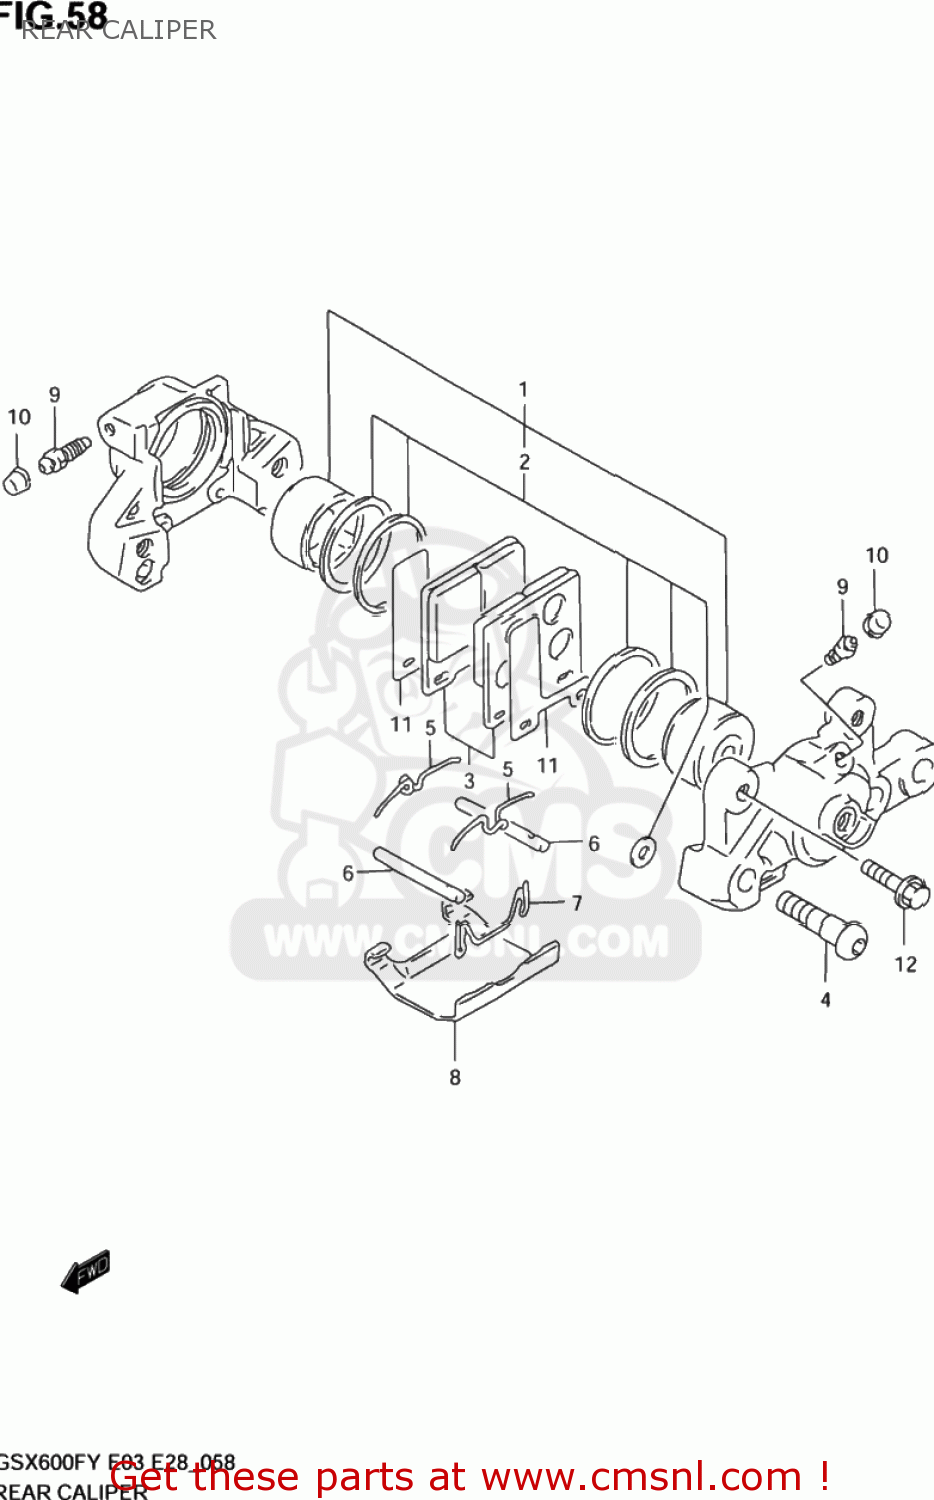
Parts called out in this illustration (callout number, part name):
1	PISTON SET
2	SEAL SET,PISTON
3	PAD SET (NAS)
4	BOLT,HOUSING
5	SPRING
6	PIN,PAD
7	CLIP,PAD PIN
8	COVER
9	BLEEDER
10	CAP,BLEEDER PLUG
11	SHIM
12	BOLT
